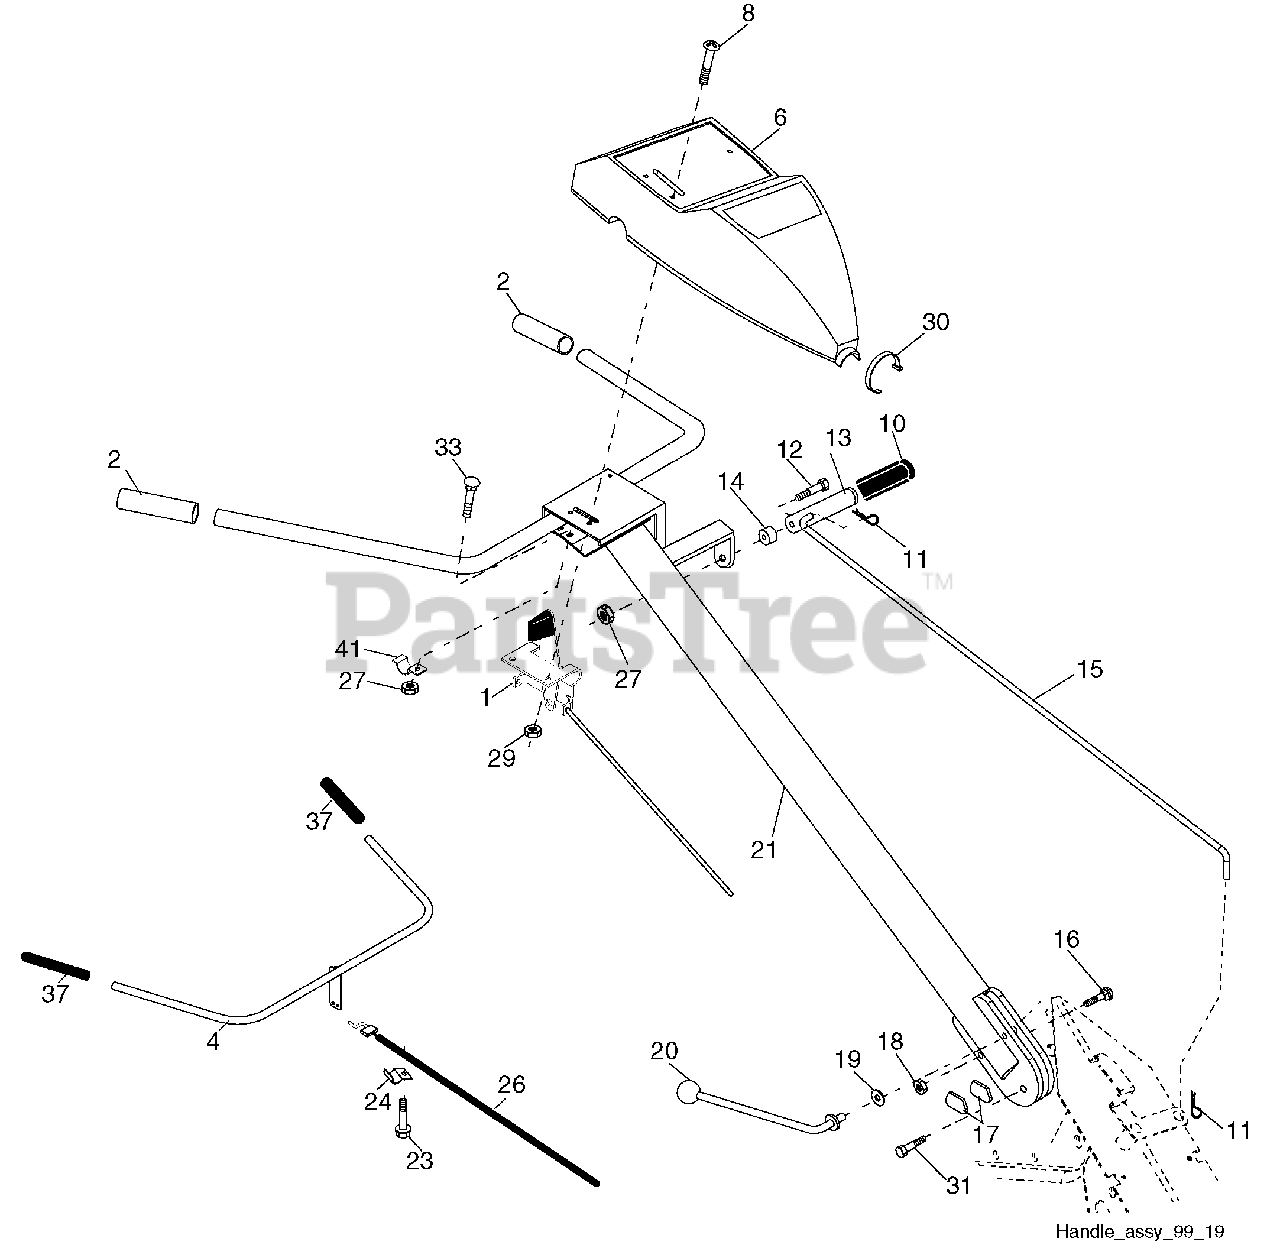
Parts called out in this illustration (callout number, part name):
1	Control, Throttle
2	Grip, Handle
4	Bar Assembly, Control
6	Panel, Control
8	Screw, Phd. #10-24
10	Grip, Handle
11	Clip, Hairpin
12	Bolt, Shoulder
13	Handle, Shift
14	Grommet, Rubber
15	Rod, Shift
16	Bolt, Carriage 3/8-16 x 1 Gr. 5
17	Lock, Handle
18	Nut, Crownlock 3/8-16 unc
19	Washer 13/32 x 1 x 11 Ga.
20	Lever, Lock, Handle
23	Screw, Hex Washer Hd. Slotted #10-24 x 1/2
24	Clip
26	Cable, Clutch
27	Nut Hex Flange 1/4-20 unc
29	Nut, Keps #10-24 unc
30	Tie, Cable
31	Bolt, Pivot
33	Bolt, Carriage 1/4-20 unc x 1/2
37	Grip, Bar, Control
41	Clamp, Bar, Control
